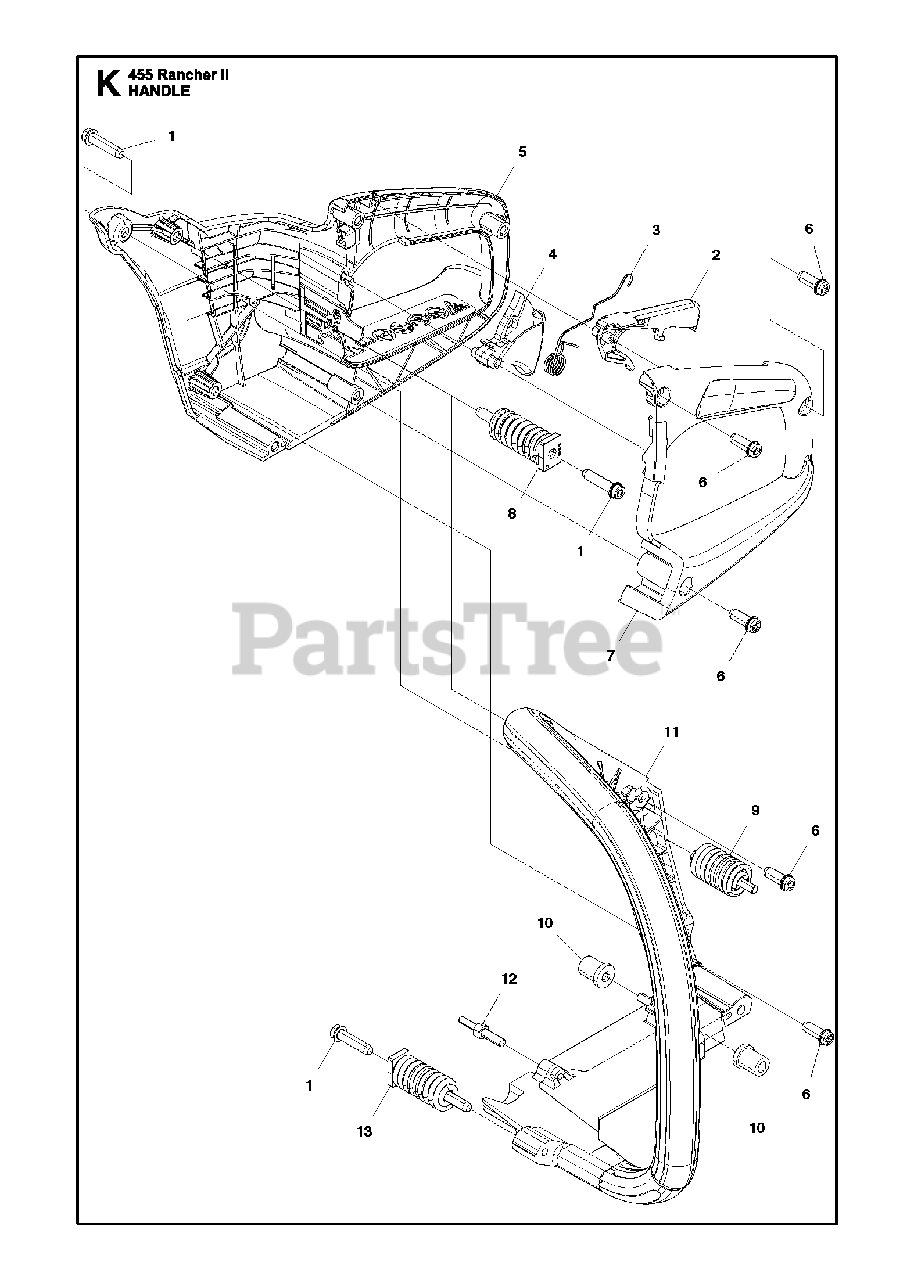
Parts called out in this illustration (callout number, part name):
1	SCREW
2	THROTTLE LOCK
4	THROTTLE TRIGGER
5	REAR HANDLE
6	SCREW
7	CAP - LEFT SIDE HANDLE
8	VIBRATIONS ABSORBER
9	VIBRATION ABSORBER
10	MOVEMENT LIMITER
11	FRONT HANDLE
